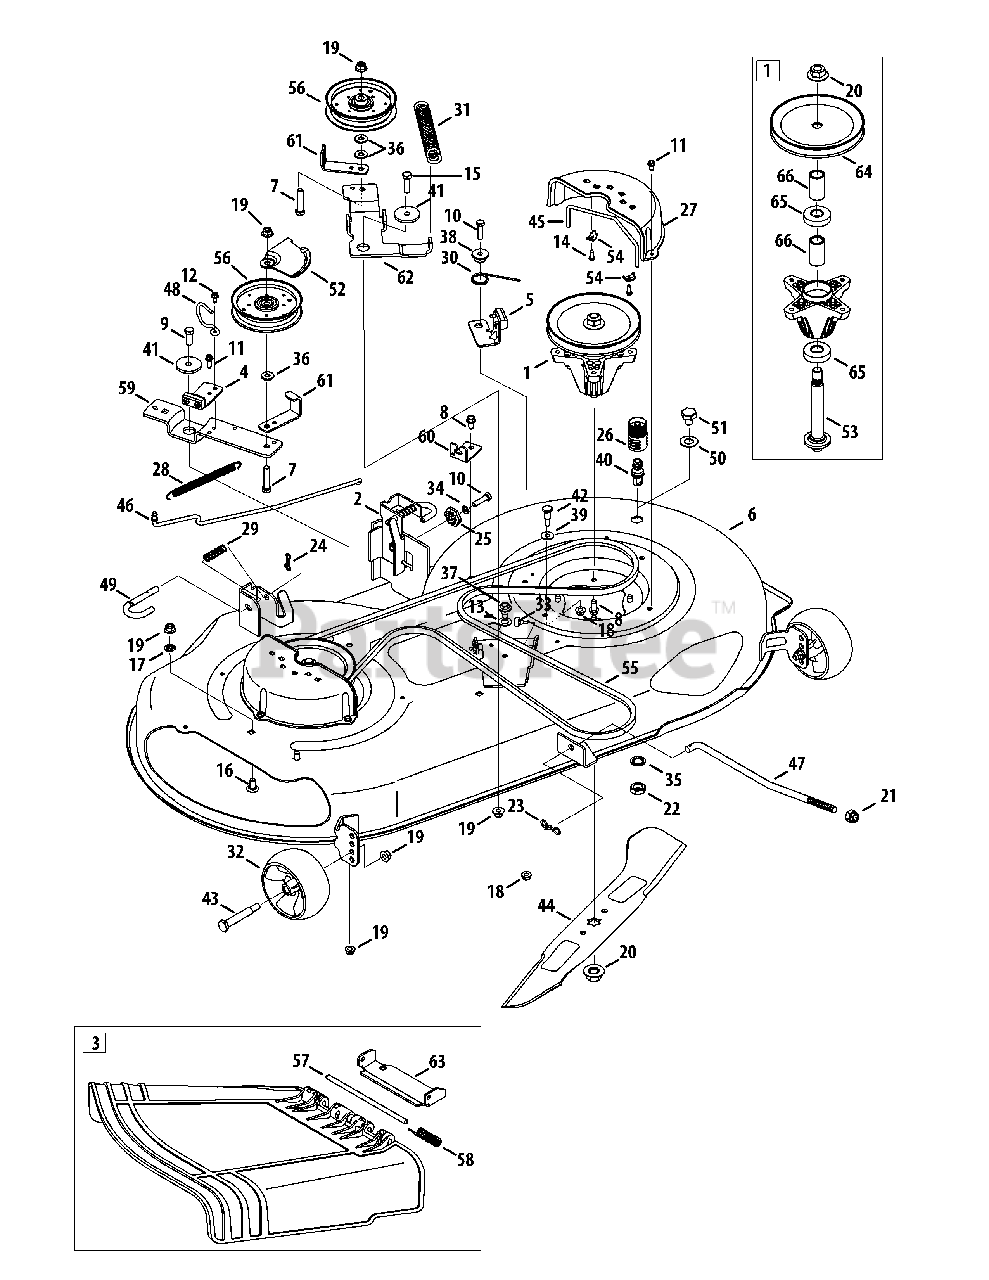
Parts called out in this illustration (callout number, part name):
1	Spindle Assembly, Pulley 6.93 Dia W/O Zerk
2	Bracket Asm, Deck, Hngr LH
3	Chute Deflector Assembly
4	Brake Asm, Deck,
5	Brake Asm, Deck, 46"
6	Deck Asm, 46t,
7	Screw, 3/8-16, 2.00, Gr5, Std
8	Screw, 5/16-18, .750, Hxindwsh
9	Screw, 3/8-16, 1.00, Gr5, Std
10	Screw, 5/16-18, 1.25, Gr5, Std
11	Screw, Tt, 1/4-20, 0.500, Hxindwsh
12	Screw, Tt, 1/4-20, 0.750, Hxindwsh
13	Washer, Flat, .474 x .879 x .064
14	Screw, B, #10-16, 0.625, Hxindwsh, Sp
15	Screw, 3/8-16, 1.25, Gr5, Std
16	Bolt, Crg, 3/8-16, 0.75, Gr1
17	Nut, Push, 3/8
18	Nut, Flglk, 5/16-18, Grf, Nylon
19	Nut, Flglk, 3/8-16, Grf, Nylon
20	Nut, Flg, 5/8-18
21	Nut, Flxlk, 1/2-13
22	Nut, Hex, M16-15
23	Pin, Cot, Bow-Tie
24	Bow-Tie Cotter Pin
25	Gear, Deck, Adj
26	Adap, Water Nozzle
27	Cover, Belt, Universal
28	Spring, Extn, .62 Dia X 6.12 Lg
29	Spring, Comp,
30	Spring, Torsn, .992 ID X 1.17 OD
31	Spring, Extn, 1.05 X 6.346
32	Wheel, Deck, 5.0 Dia Ball
33	Bumper, .62 Dia X 3
34	Washer, Lock, 5/16, Splt, Reg
35	Washer, Lock, 5/8, Int Tooth
36	Washer, Flat, .385x.870x.092
37	Shoulder Spacer, .43 x .29, 5/16-18
38	Shoulder Spacer, .50 x .145
39	Washer, Flat, .343 X .880 X .062
40	Noz, Deck, Water
41	Spacer, Shldr, .8840 X .190
42	Screw, Shld, .437 Dia X .54
43	Shld-Screw - 1/2 Dia X 2.50 Lg
44	Blade, 23.25" 2-In-1
45	Rod, Keeper, Belt
46	Rod, Cont, Brake 46"
47	Rod, Lift, Deck, Medium
48	Rod, Keeper, Belt
49	Rod, Handle Deck Rel
50	Washer, flat, .64 X 1.24 X .06
51	Plug, Bolt, M16 X 1.5
52	Belt Guide
53	Spindle Shaft
54	Clamp, Casing
55	Belt, V-Type, A Sec X 103.24
56	Pulley, Idler, 4.25"Dia
57	Hinge Pin
58	Torsion Springing
59	Bracket, Idler, Piv
60	Bracket, Cable, Deck Engage
61	Bracket, Guard, Belt, Pulley
62	Bracket, Idler, 46" Lh
63	Chute Bracket
64	Deck Pulley, 6.93 DIA
65	Ball Bearing, .787ID X 1.85 ODX.551
66	Spacer, .792 X 1.060 X 1.860 LG
